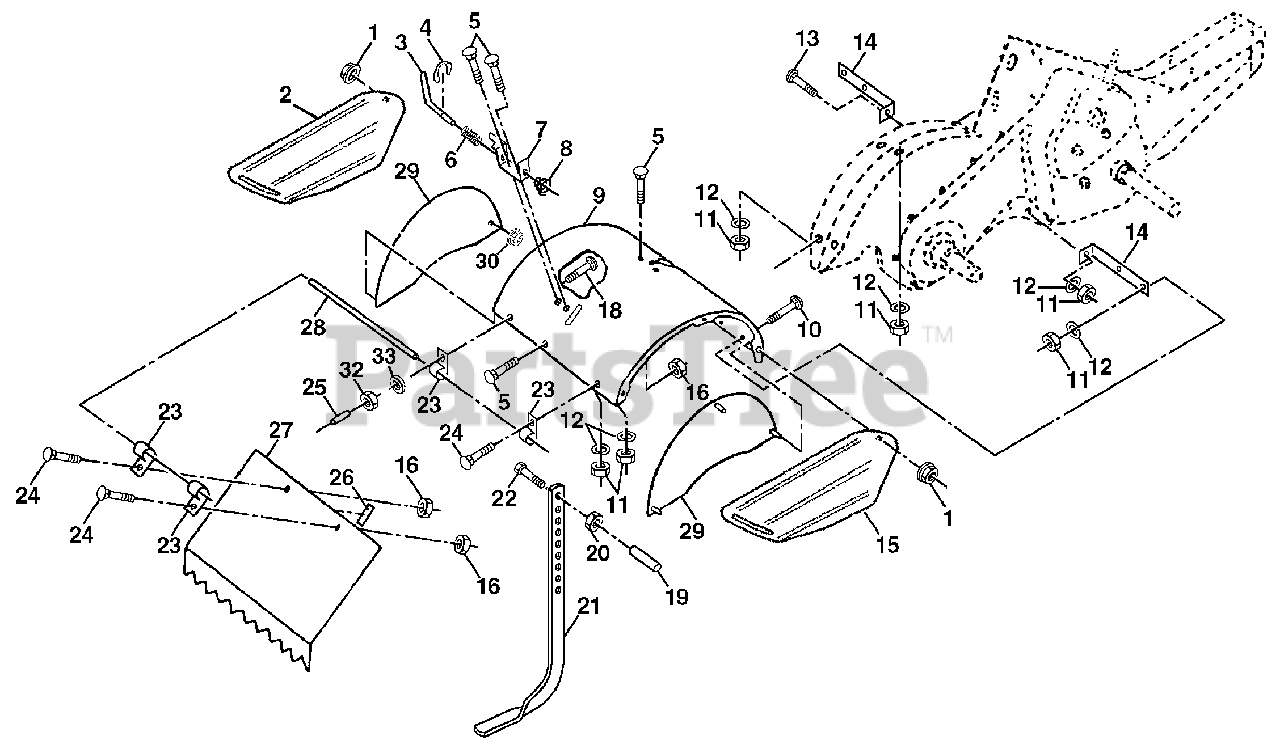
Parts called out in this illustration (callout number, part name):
1	Nut, Flange 5/16-18
2	Shield, Side, Outer L. H.
3	Pin, Stake, Depth
4	Ring, Klip
5	Bolt, Carriage 5/16-18 x 3/4 Gr. 5
6	Spring
7	Bracket, Latch
8	Spring, Depth Stake
9	Shield, Tine
10	Bolt, Carriage 5/16-18 UNC x 1
11	Nut, Hex 5/16-18
12	Washer, Lock 5/16
13	Bolt, Carriage 5/16-18 x 1-1/4
14	Bracket, Shield Tine
15	Shield, Side, Outer R.H.
16	Nut, Hex Flange 1/4-20 UNC
18	Bolt, Carriage 1/4-20 x 1-1/4 Gr. 5
19	Grip
20	Nut, Hex 3/8-16
21	Stake, Depth
22	Bolt, Hex 3/8-16 x 2
23	Hinge
24	Bolt, Carriage 1/4-20 x 1/2 Gr. 5
25	Cap, Vinyl
26	Pad, Idler
27	Shield, Leveling
28	Pin, Hinge
29	Shield, Side
30	Locknut, Flange 5/16-18
32	Nut Fin Hex 1/4-20 UNC
33	Washer Lock Hvy Helical 1/4
